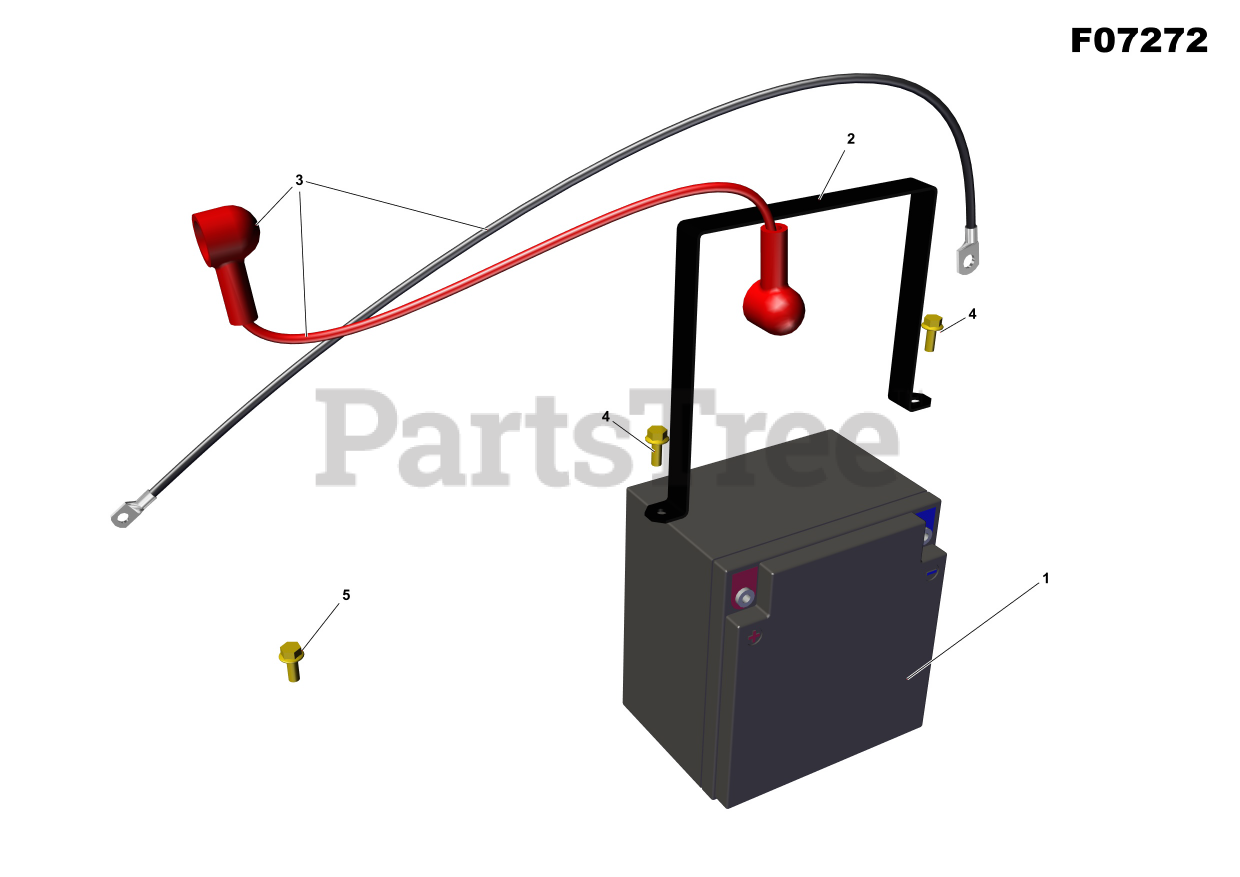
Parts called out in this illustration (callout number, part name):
1	Battery 12V 026Ah
2	Fixing bracket
3	Battery wiring harness KOHLER CH640
